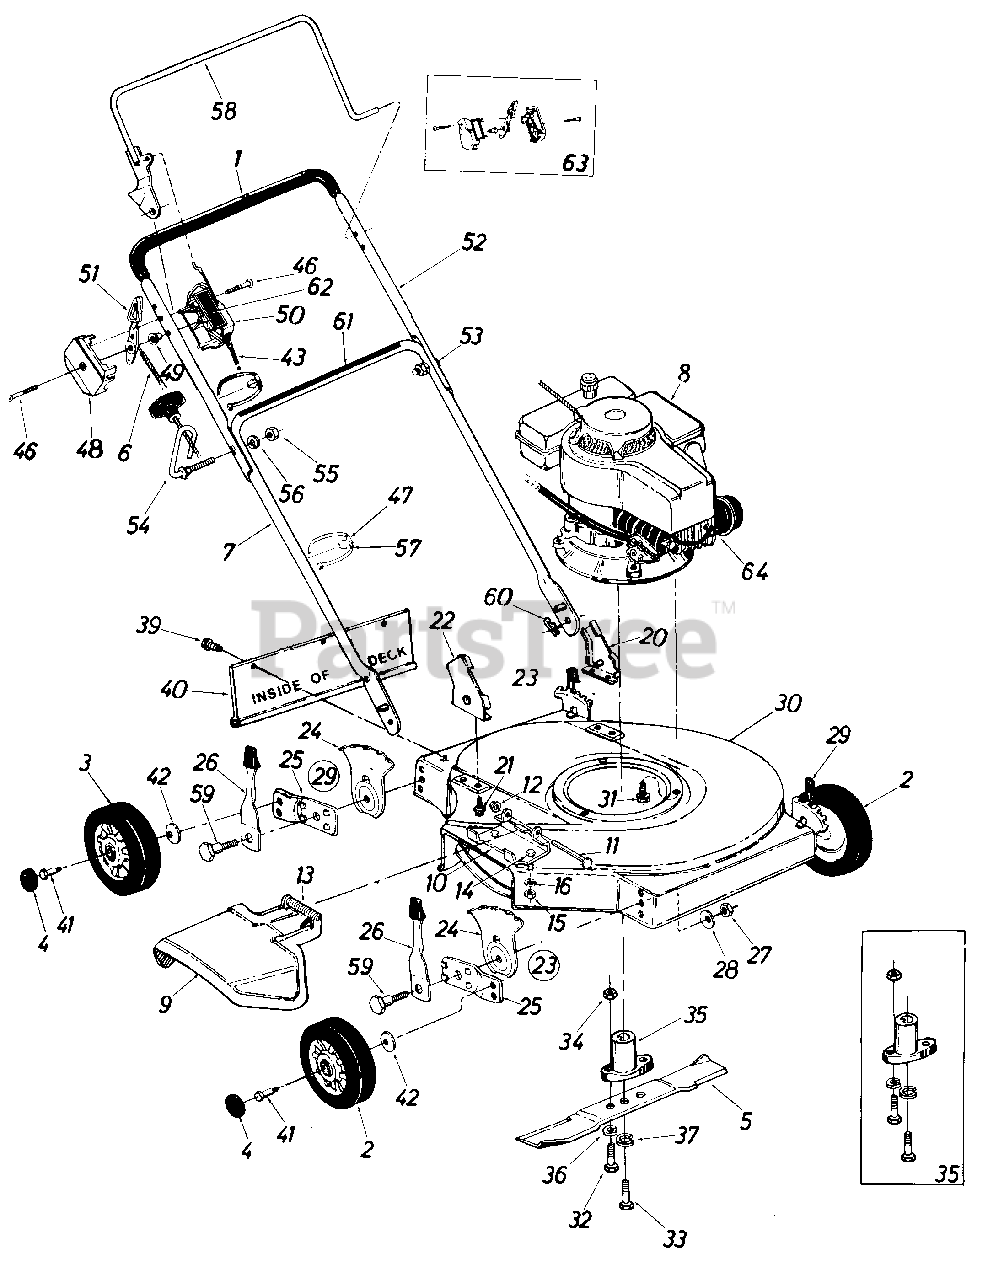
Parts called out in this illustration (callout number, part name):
2	Front Wheel Ass'y. Comp. 8 x 1.75
3	Rear Wheel Ass'y. Comp. 8x 1.75
4	Hub Cap
5	20" Blade
6	Throttle Wire 45"
7	Lower Handle
9	Chute Deflector Ass'y. Comp.
10	Adapter Plate
11	Pivot Pin
12	Push Cap 1/4" Rod
13	Torsion Spring
14	Hex Bolt 1/4-20 x .50" Lg.
15	Hex Nut 1/4-20 Thd.
16	L-Wash. 1/4" I.D.
20	Handle Brkt. Ass'y. L.H.
21	Hex Wash. Hd. B-Tap Scr. 5/16-18 x .50" Lg.
22	Handle Brkt. Ass'y. R.H.
23	Height Adj uster Ass'y. Comp. R.H.
24	Index Plate
25	Pivot Bar
26	Spring Lever Ass'y. w/Knob
27	Hex Nut 3/8-16 Thd.
28	Bell-Wash. .39" I.D. x 1.13" O.D.
29	Height Adjuster Ass'y. Comp. L.H.
30	20" Deck Ass'y. Comp.
31	Hex Wash. Hd. TT-Tap Scr. 3/8-16 x 1.0" Lg.
32	Hex Bolt 5/16-18 x 1.0" Lg. (Grade 8)
33	Hex Bolt 3/8-24 x 2.25" Lg. (Grade 5)
34	Hex Nut 5/16-24 Thd.
35	Blade Adapter Kit
36	L-Wash. 5/16" I.D.
37	L-Wash. 3/8" I.D. H.D.
39	Hex Wash. Hd. AB-Tap Scr. 1/4" X .62" Lg.
40	Rear Flap Ass'y.
41	Shld. Bolt .498" Dia. x 1.45"
42	Bell-Wash. .400" I.D. x .88" O.D.
43	Control Cable 43"
46	Truss Mach. Self-Tap Scr. #12 x 1.5" Lg.
47	Cable Anchor
48	Control Panel Half
49	Control Disc Pin
50	Clutch Panel Half
51	Throttle Control Lever
52	Upper Handle
53	Curved Carriage Bolt 5/16-18 x 1.38" Lg.
54	Rope Guide Bolt
55	Hex Nut 5/16-18 Thd.
56	L-Wash. 5/16" I.D.
57	Cable Tie
58	Control Handle Ass'y. R.H.
59	Shld. Bolt .500" Dia. x .375
60	Hairpin Cotter
61	Instruction Label Handle
62	Control Label Throttle
63	Kit Control Housing Comp.
64	Spark Plug Boot
